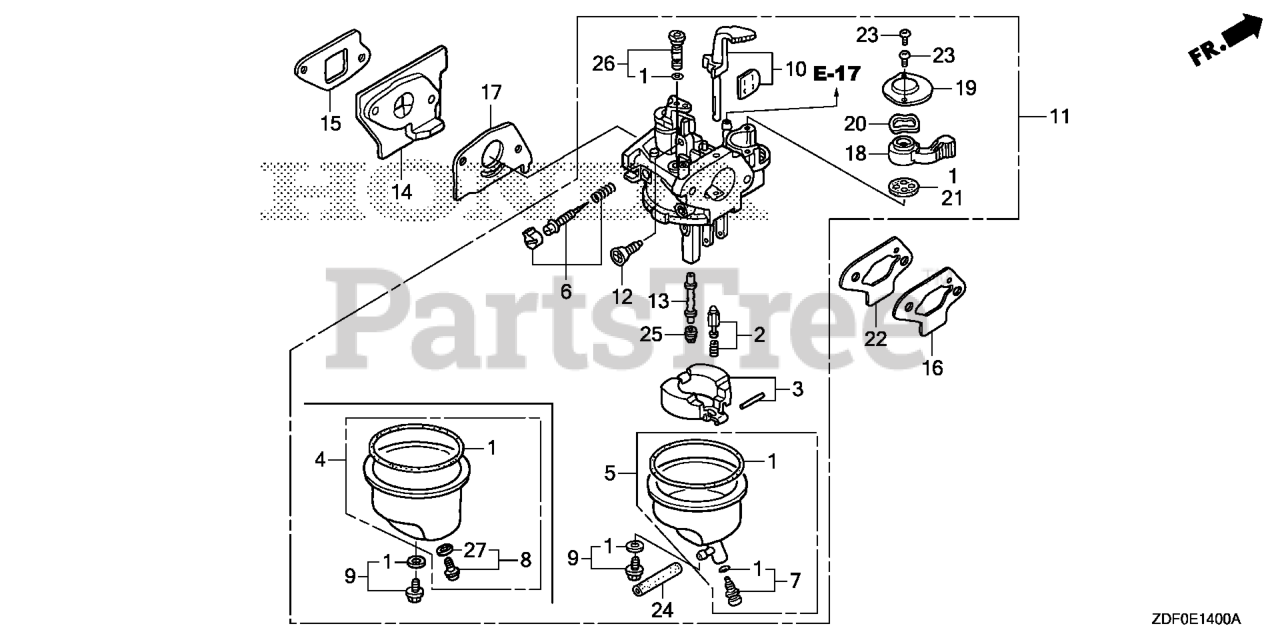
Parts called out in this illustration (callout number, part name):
1	GASKET SET
2	VALVE SET, FLOAT (CARBURETOR NO.) (SEAT NOT INCLUDED)
5	CHAMBER SET, FLOAT (CARBURETOR NO.)
6	SCREW SET
7	SCREW SET, DRAIN (CARBURETOR NO.)
9	SCREW SET (CARBURETOR NO.)
10	CHOKE SET (CARBURETOR NO.)
11	CARBURETOR ASSY. (BF32G A)
12	SCREW, THROTTLE STOP
13	NOZZLE, MAIN
14	INSULATOR, CARBURETOR
15	GASKET, INSULATOR (ENGINE NO.)
16	SPACER, CARBURETOR
17	GASKET, CARBURETOR
18	LEVER, VALVE (CARBURETOR NO.)
19	PLATE, LEVER SETTING (CARBURETOR NO.)
20	SPRING, PETCOCK LEVER (CARBURETOR NO.)
21	GASKET, VALVE
22	GASKET, AIR CLEANER
23	SCREW, PAN (3X6)
24	BULK HOSE, VINYL (3.5X6.5X8000) (9500(95003-05001-60M) (CARBURETOR NO.)
25	JET, MAIN (#50) Use from Engine SN BF12A B.
25	JET, MAIN (#52) Use from Engine SN BF12A B.
25	JET, MAIN (#55) Use from Engine SN BF22B D.
26	JET SET, PILOT (#38)
